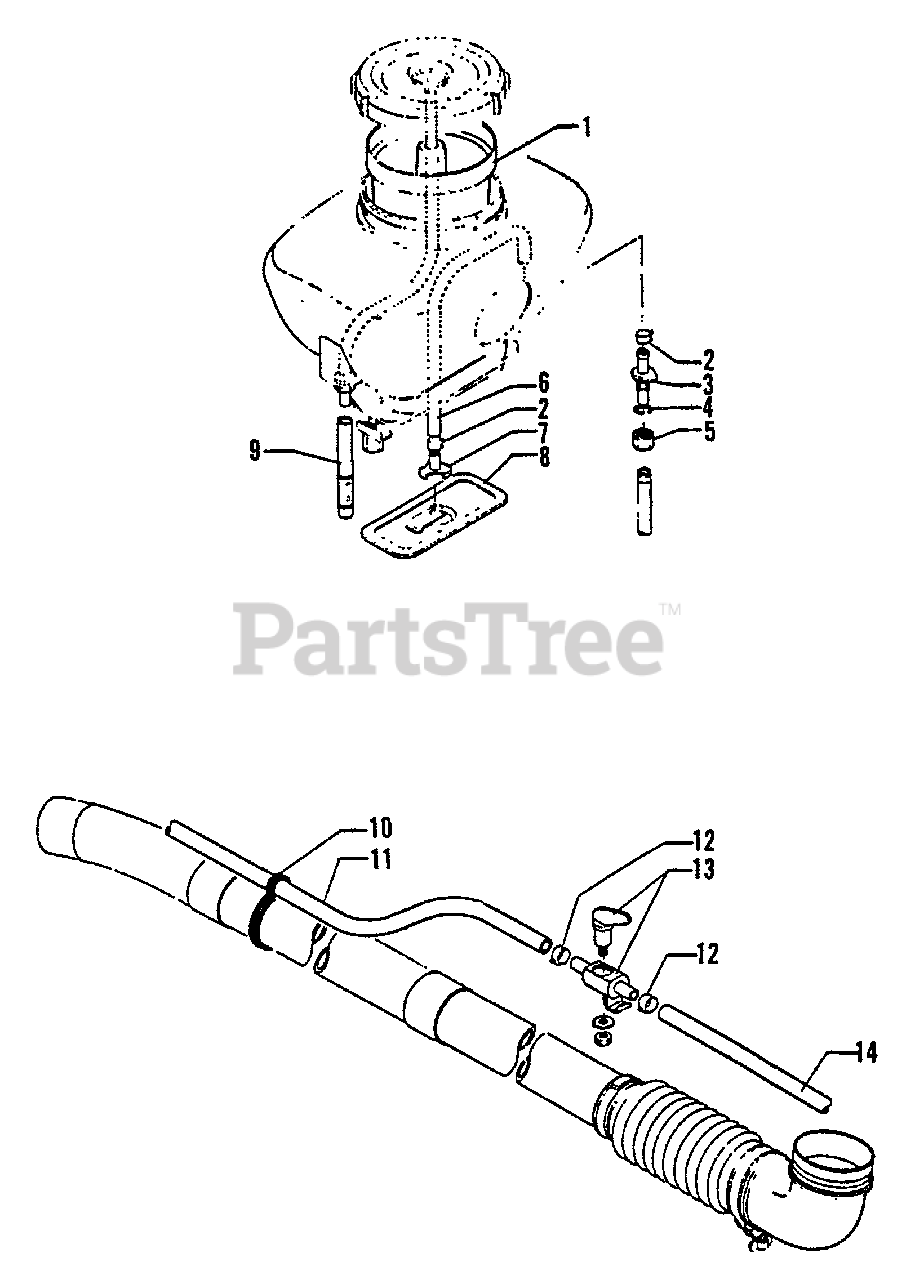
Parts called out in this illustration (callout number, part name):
2	CLIP - 14
3	CONNECTOR, PIPE
4	O-RING 3×13
6	HOSE, FLUID
7	MOUTH, SUCTION
10	CLIP
11	PIPE, DISCHARGE 9×13×720L
12	CLIP - 14
13	VALVE ASSY
14	TUBE, VINYL
